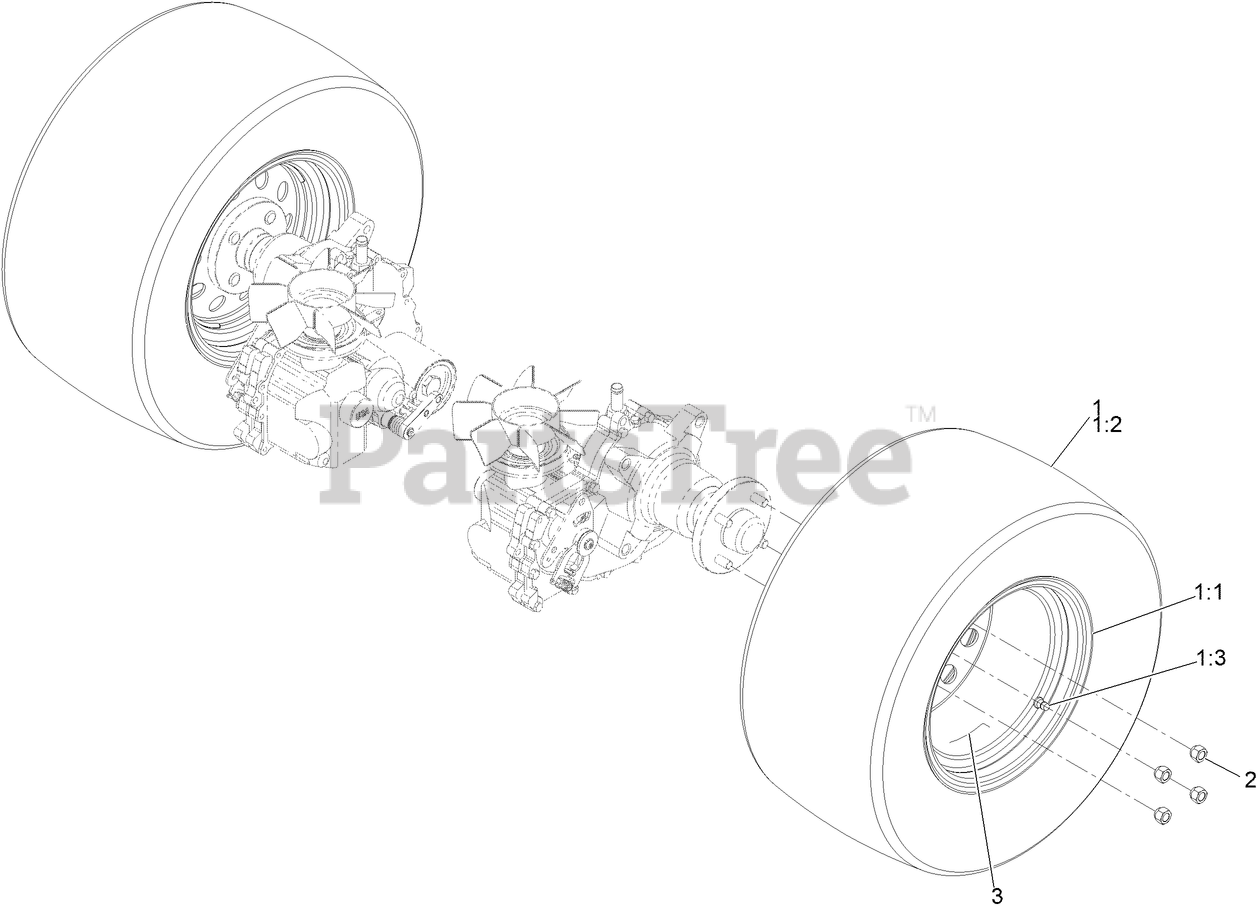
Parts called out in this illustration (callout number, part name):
1	ASM-Wheel And Tire
1:1	Rim, 24X12-12
1:3	VALVE
2	NUT-LUG
3	DECAL-TORQUE, WHEEL NUT
